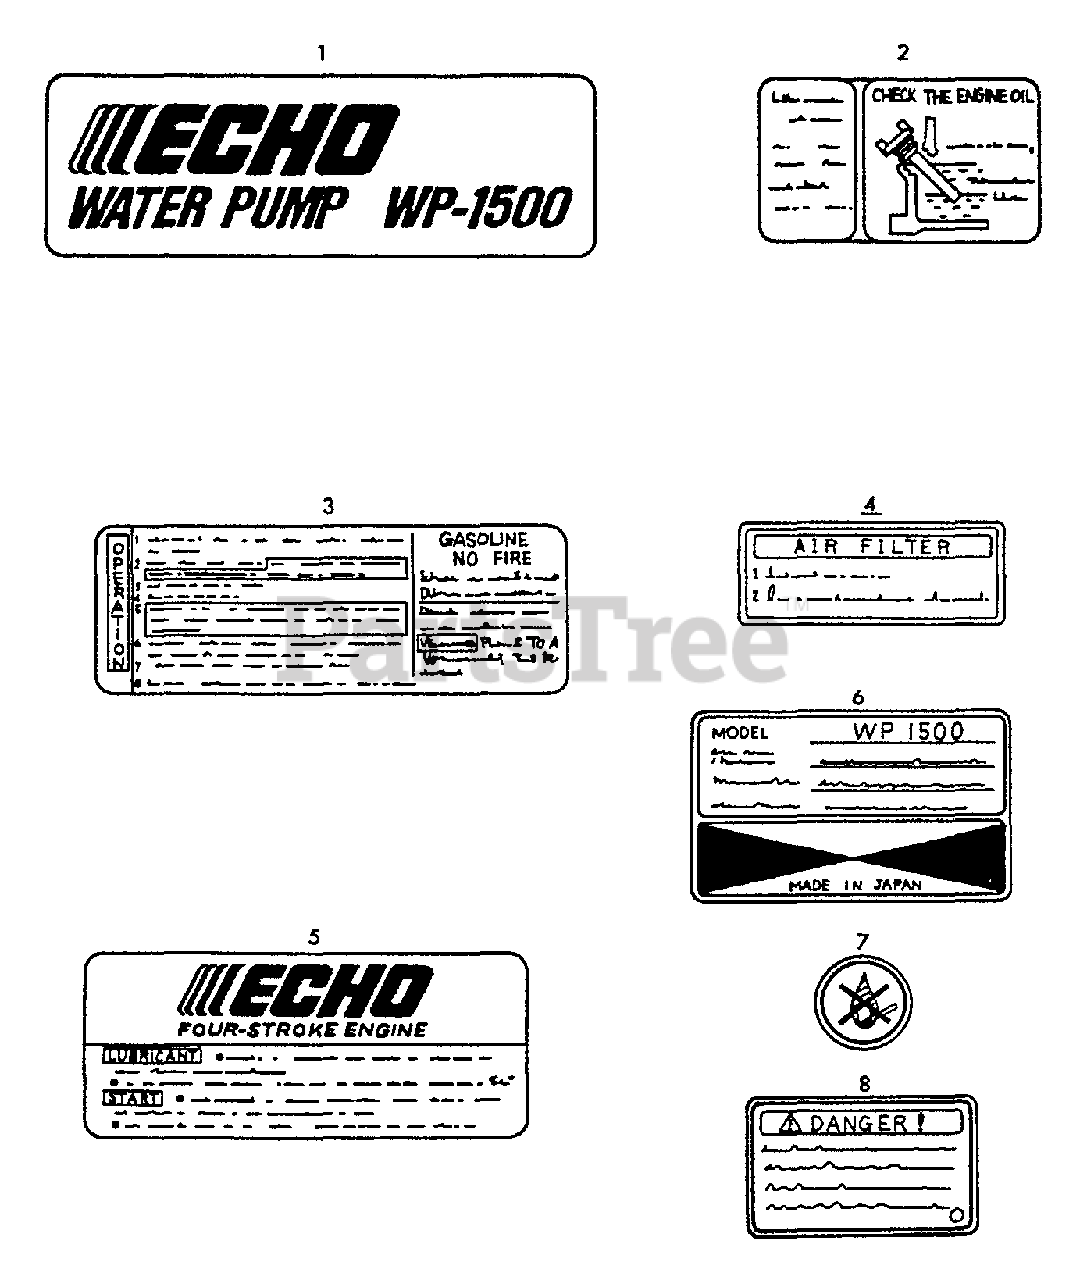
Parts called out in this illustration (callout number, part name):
1	LABEL - MODEL WP1500
2	LABEL - OIL
3	LABEL - OPERATION
4	LABEL - AIR CLEANER
5	LABEL - ECHO
6	LABEL, ENGINE NAME
7	LABEL - NON FIRE
8	LABEL - DANGER
